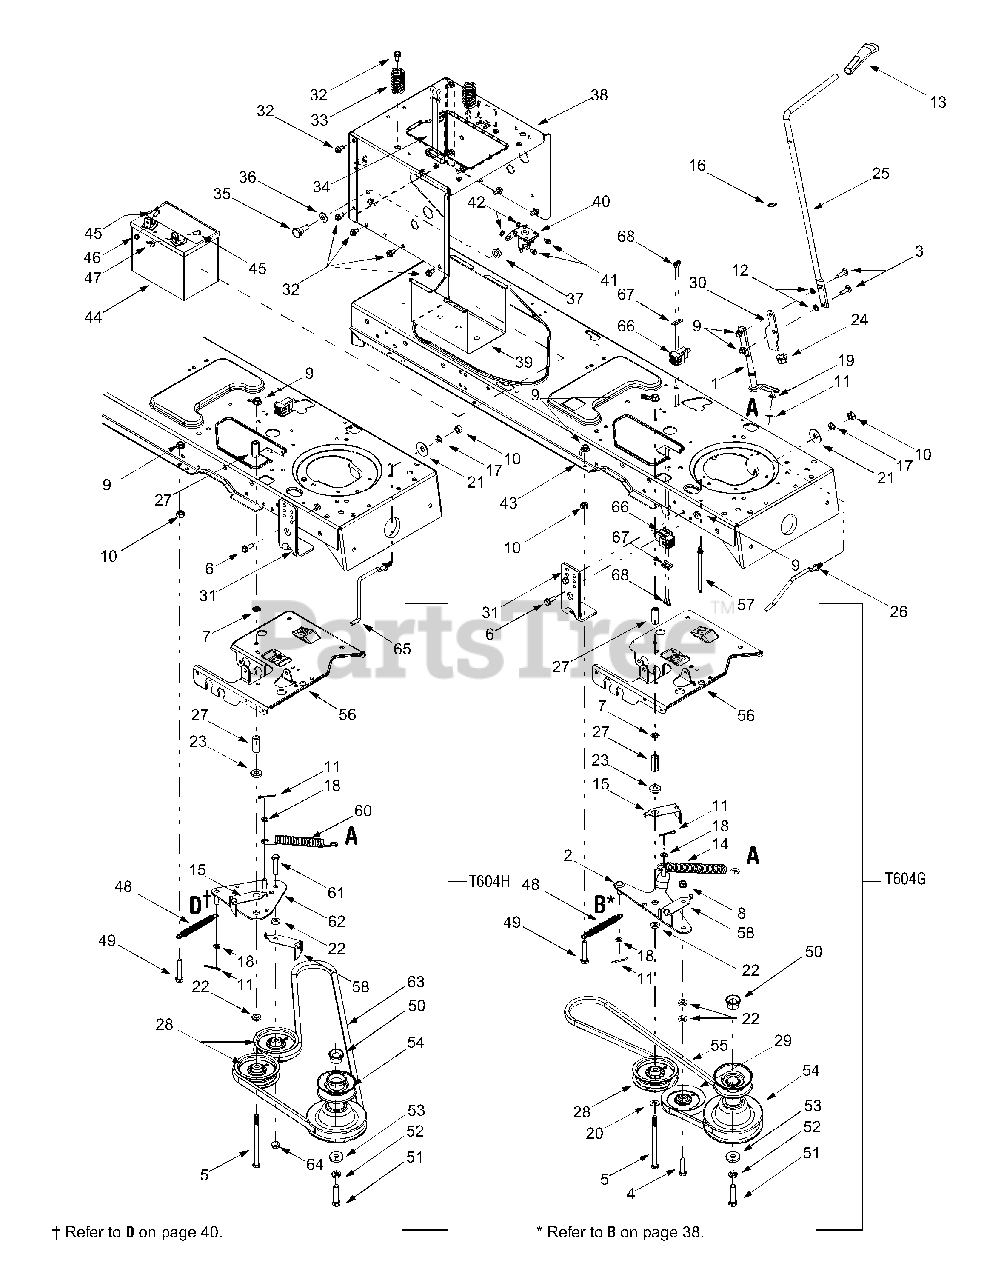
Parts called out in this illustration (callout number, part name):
1	PTO Engage Lever Assembly
4	Hex Cap Screw, 3/8-16 x 1.5
5	Hex Cap Screw, 3/8-16 x 5.5
6	Hex Head Washer Screw, 5/16-18 x .875
7	Push Nut, 3/8
8	Flange Lock Nut, 3/8-16
9	Flange Lock Nut, 5/16-18
10	Hex Nut, 5/16-18
11	Cotter Pin, 1/8 x 1.25
12	Speed Nut, .3125
13	PTO Knob
14	Extension Spring, .75 x 6.75
15	Belt Guard
16	Flat Washer, .510 x .750 x .033
17	Lock Washer, 5/16
18	Flat Washer, .385 x .62 x .063
19	Flat Washer, 5/16
20	Flat Washer, .406 x .875 x .059
21	Bell Washer, .39 x 1.13 x .062
22	Flat Washer, .407 x .812 x .135
23	Shoulder Spacer, .380
24	Hex Split Flange Bearing, .5
26	Belt Keeper Rod
27	Spacer, 3/8 x 1.54
28	Idler Pulley, 3.5
29	Idler Pulley, 4.0
32	Self Tapping Screw, 5/16-18 x .625
33	Compression Spring, 1.28 x 3.125
34	Battery Strap
35	Shoulder Screw, .625 x .5, 7/16-20
36	Bell Washer, .45 x 1.0 x .062
37	Flange Lock Nut, 7/16-20
41	Self Tapping Screw, 1/4-20 x .5
42	Lock Washer, 1/4
45	Hex Cap Screw, 1/4-20 x .62
46	Hex Sems Nut, 1/4-20
47	Wing Nut, 1/4-20
48	Extension Spring, .50 x 5.0
49	Hex Cap Screw, 5/16-18 x 1.75
50	Spacer Cup
51	Hex Head Cap Screw, 7/16-20 x 1.25
52	Lock Washer, 7/16
53	Flat Washer, .450 x 1.25
54	Engine Pulley, 3.56 OD x 5.56
55	PTO Belt (Model T604G)
57	Keeper Pin, 5/16 x 4.75
58	Belt Guard
60	Extension Spring, .75 x 6.75
61	Hex Cap Screw, 3/8-16 x 1.75
63	PTO Belt (Model T604H)
64	Flange Lock Nut, 3/8-16
65	Belt Keeper Rod
66	Switch
67	Switch Plate
68	Screw, #10-16 x .5
